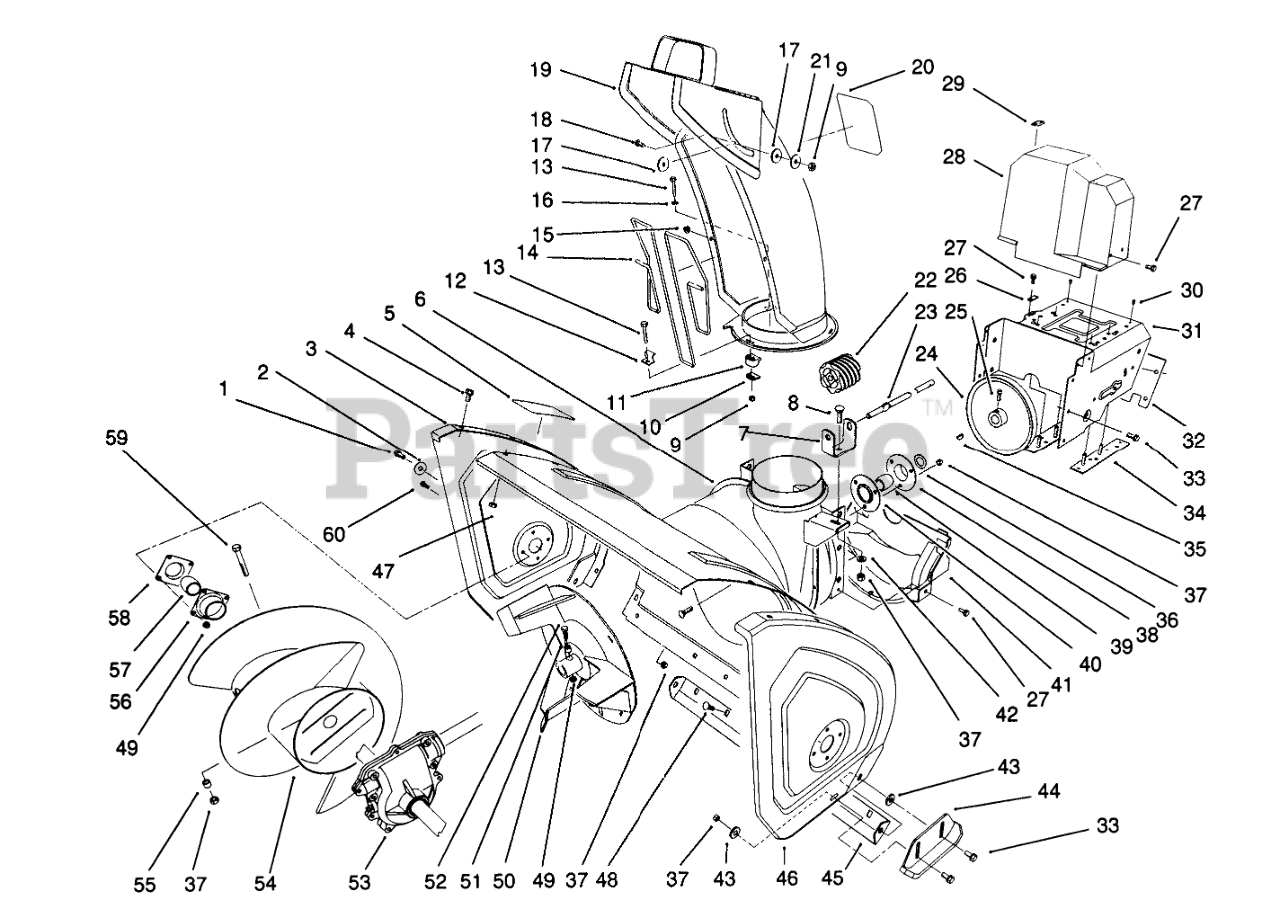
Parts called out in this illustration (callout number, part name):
1	SCREW-HH
2	WASHER
3	Plate-Side
4	SCREW-HHF
5	DECAL-WARNING, AUGER
6	Housing-24"
7	BRACKET-WORM, CHUTE
8	BOLT-CARR
9	NUT-LOCK, NI
10	PLATE-RETAINER, CHUTE
11	RETAINER-CHUTE
12	CLIP-GUARD, CHUTE
13	SCREW-HSH
14	GUARD-CHUTE
15	NUT-PUSH
16	WASHER-FLAT
17	WASHER-PLASTIC
19	Assembly
20	Decal-Danger
21	WASHER-FLAT
22	GEAR-WORM
23	ROD-CHUTE, LOWER
24	PULLEY-IMPELLER
25	SCREW-SET, SQH
26	RETAINER-CABLE
27	SCREW-HWH
28	COVER-BELT, UPPER
29	COVER-CABLE
30	RIVET-POP
31	Frame-Engine
32	Cover-Frame, Engine
33	SCREW-HHF
34	LH FRAME PLATE ASM
35	KEY-WOODRUFF
36	WASHER-THRUST
37	NUT-LOCK, NI
38	Flange-Bearing (Front )
39	BEARING-BALL
40	Flange-Bearing ((Rear)
41	Cover-Belt (Lower)
42	WASHER-PLAIN
43	WASHER
44	Skid
45	Blade-Scraper
46	Plate-Side
47	NUT-LOCK, NI
48	SCREW-CARR
49	NUT-LOCK, NI
50	Impeller
51	SPACER
52	SCREW-HHF
53	AUGER GEARCASE ASM
54	Auger-R.H.
55	SPACER-HUB, AUGER
56	BEARING-FLANGE, FRONT
57	BEARING
58	BEARING-FLANGE, REAR
59	Auger Bolt
60	SCREW-HH
